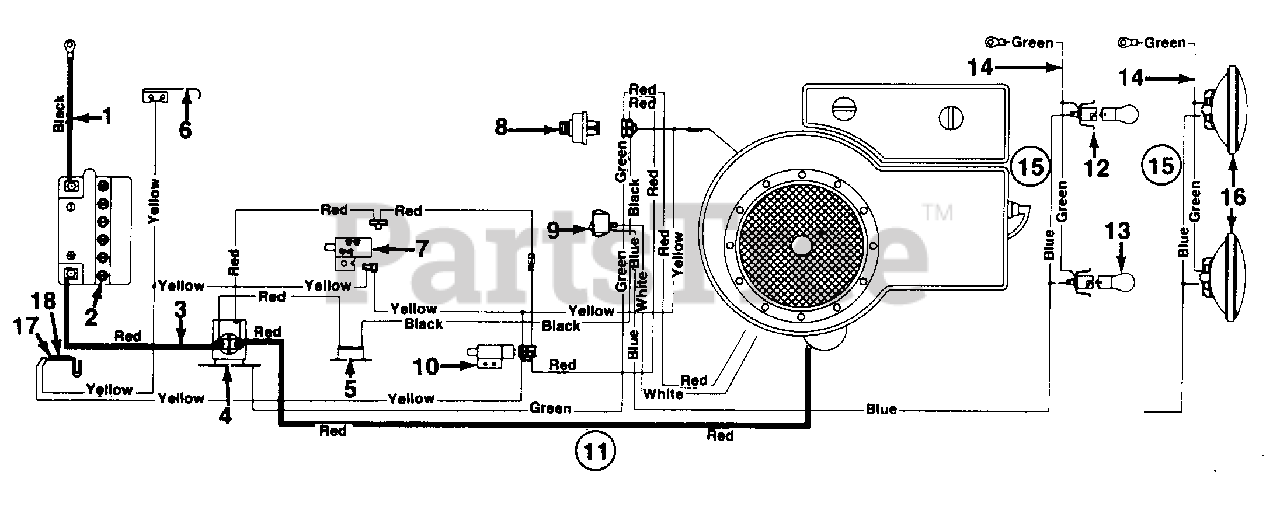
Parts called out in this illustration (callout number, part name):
1	Ground Wire
2	Battery
3	Electric Wire-8.0" Lg.
4	Solenoid
5	Circuit Breaker
6	Spring Switch
7	Safety Switch
8	Ignition Switch
9	Light Switch
10	Safety Switch
11	Harness
12	Socket
13	Bulb
14	Ground Wire
15	Headlight Harness
16	Headlight
17	Safety Switch
18	Safety Switch
